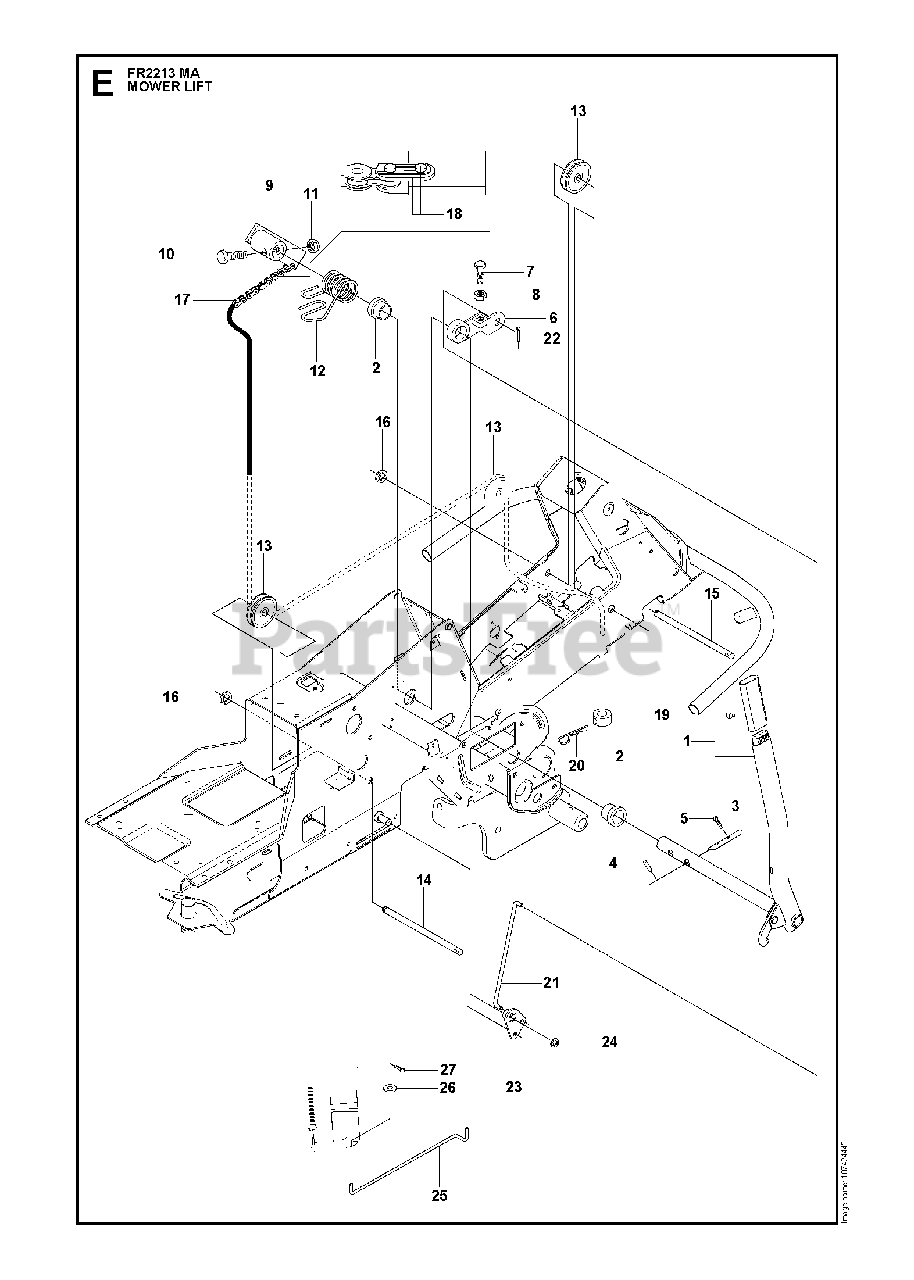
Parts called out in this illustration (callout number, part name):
1	LIFTING LEVER ASSY
2	BUSH
3	RP PIN
5	SPLIT PIN
6	LEVER CLUTCH
9	LIFTING ARM
16	LOCK RING
21	CONNECTION ROD
22	SPLIT PIN
24	RETAINING RING
25	CONNECTION ROD
27	SPLIT PIN
